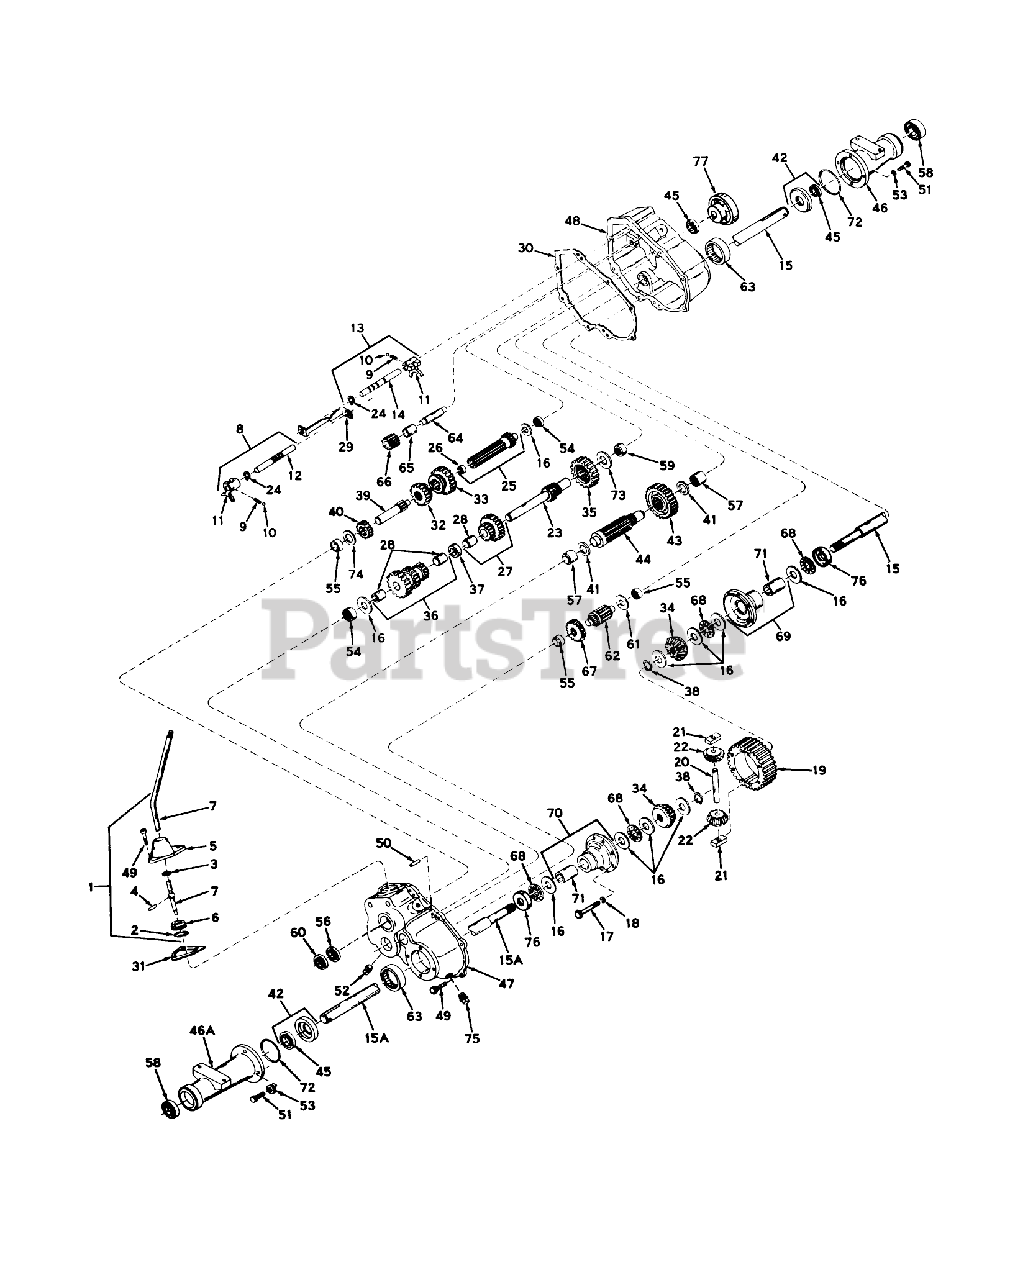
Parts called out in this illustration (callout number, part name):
1	Lever Housing Assy., Shift (Incl. Nos. 2 thru 7)
2	Ring-Snap
3	O Ring
4	Roll Pin
5	Housing-Shift Lever
6	Keeper, Shift Lever
7	Lever, Shift
8	Rod Assy., Shift (Incl. Nos. 9 thru 12 24)
9	Spring
10	Piston ASM
11	Shift Fork
12	Rod, Shifter
13	Rod Assy., Shift (Incl. Nos. 9, 10, 11, 14 24)
14	Rod, Shifter
15	Axle, R.H.
15A	Axle, L.H.
16	Washer
17	Screw (1/4-20 x 2-1/2)
18	Lockwasher
19	Gear-Ring
20	Pin-Drive
21	Biock-Drive
22	Pinion-Bevel
23	Shaft Gear-Brake
24	Ring-Snap
25	Shaft Bearing Assy., Pinion (Incl. No. 26)
26	Bearing
27	Gear Cluster Assy. (Incl. No. 28)
28	Bushing
29	Stop-Shifter
30	Gasket-Case Cover
31	Gasket-Lever Housing
32	Gear, Shifting
33	Gear, Shifting
34	Gear-Bevel
35	Gear-Spur
36	Gear Cluster Assy. (Incl. No. 28)
37	Spacer
38	Ring-Snap
39	Shaft, Input
40	Gear (10 teeth)
41	Washer-Thrust
42	Seal Retainer Assy., Oil(Incl. No. 45)
43	Gear-Output
44	Pinion-Output
45	Seal-Oil
46	Housing, R.H. Axle
46A	Housing, L.H. Axle
47	Case Assy., Transaxle (Incl. Nos. 54, 55, 57 63)
48	Cover Assy., Transaxle (Incl. 54, 55, 57, 59 63)
49	Screw
50	Dowel Pin
51	Screw (5/16-18 X 7/8)
52	Plug-Magnetic Drain
53	Lockwasher
54	Bearing-Needle
55	Bearing, Needle
56	Bearing
57	Bearing-Needle
58	Bearing-Ball
59	Bearing-Needle
60	Seal-Oil
61	Washer
62	Shaft Pinion
63	Bearing Needle
64	Shaft-Reverse Idler
65	Spacer-Reverse Idler
66	Idler Reverse
67	Gear-Spur (22 Teeth)
68	Bearing-Thrust
69	Carrier Assy., Differential (Incl. No. 71)
70	Carrier Assy., Differential (Incl. No. 71)
71	Bushing
72	O-Ring
73	Washer-Thrust
74	Washer
76	Race-Thrust
77	Drum, Brake
